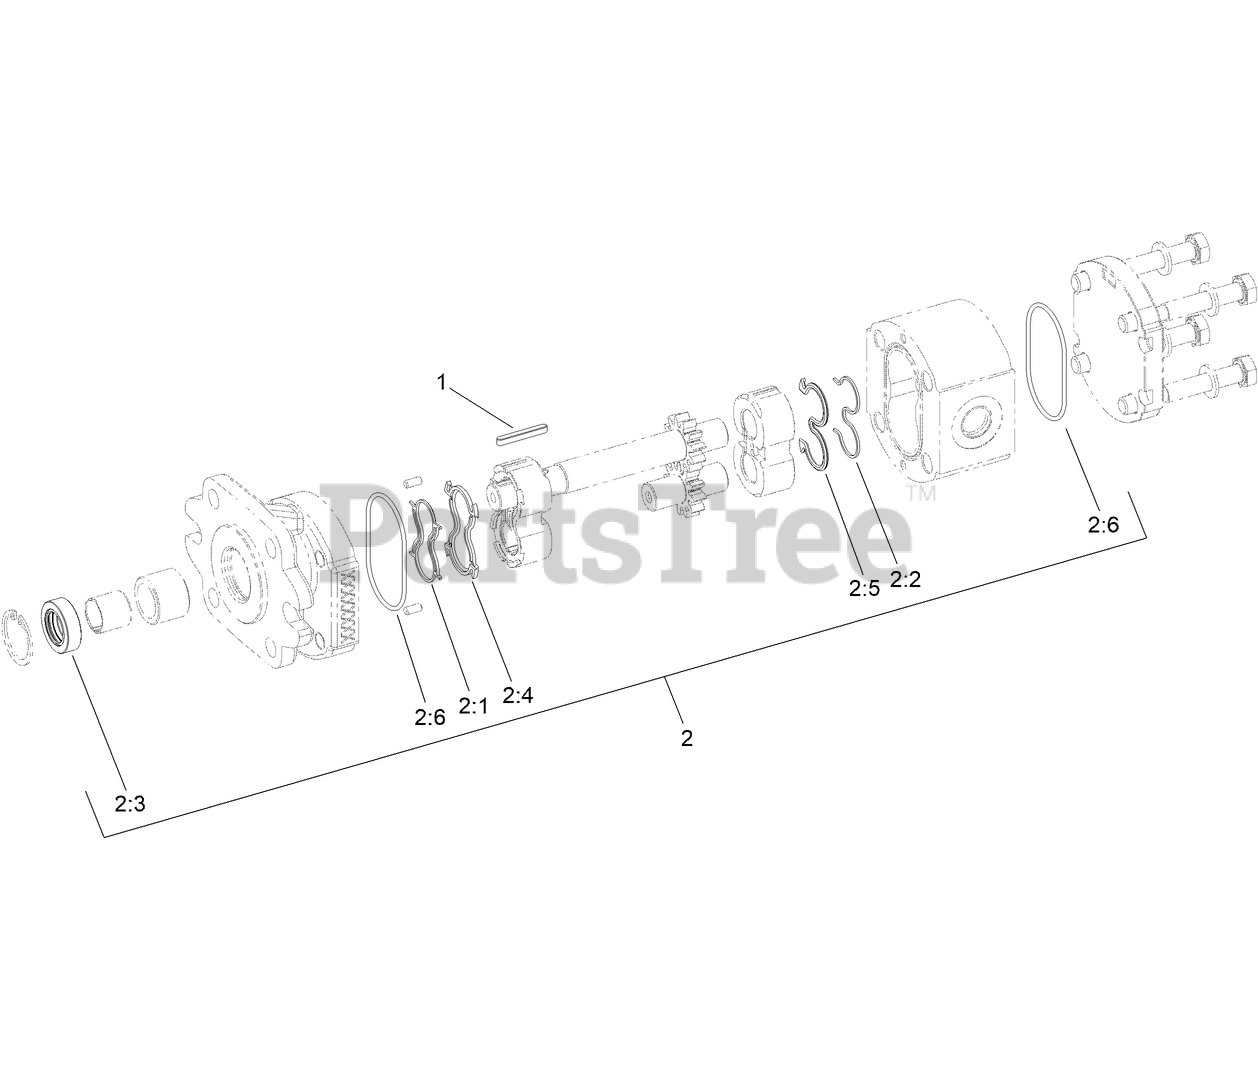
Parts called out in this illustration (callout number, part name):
1	KEY-SQUARE
2	SEAL KIT
2:1	Seal-Anti Extrusion
2:2	Seal-Anti Extrusion
2:3	Seal-Shaft
2:4	Seal-Upper
2:5	Seal
2:6	O-Ring
